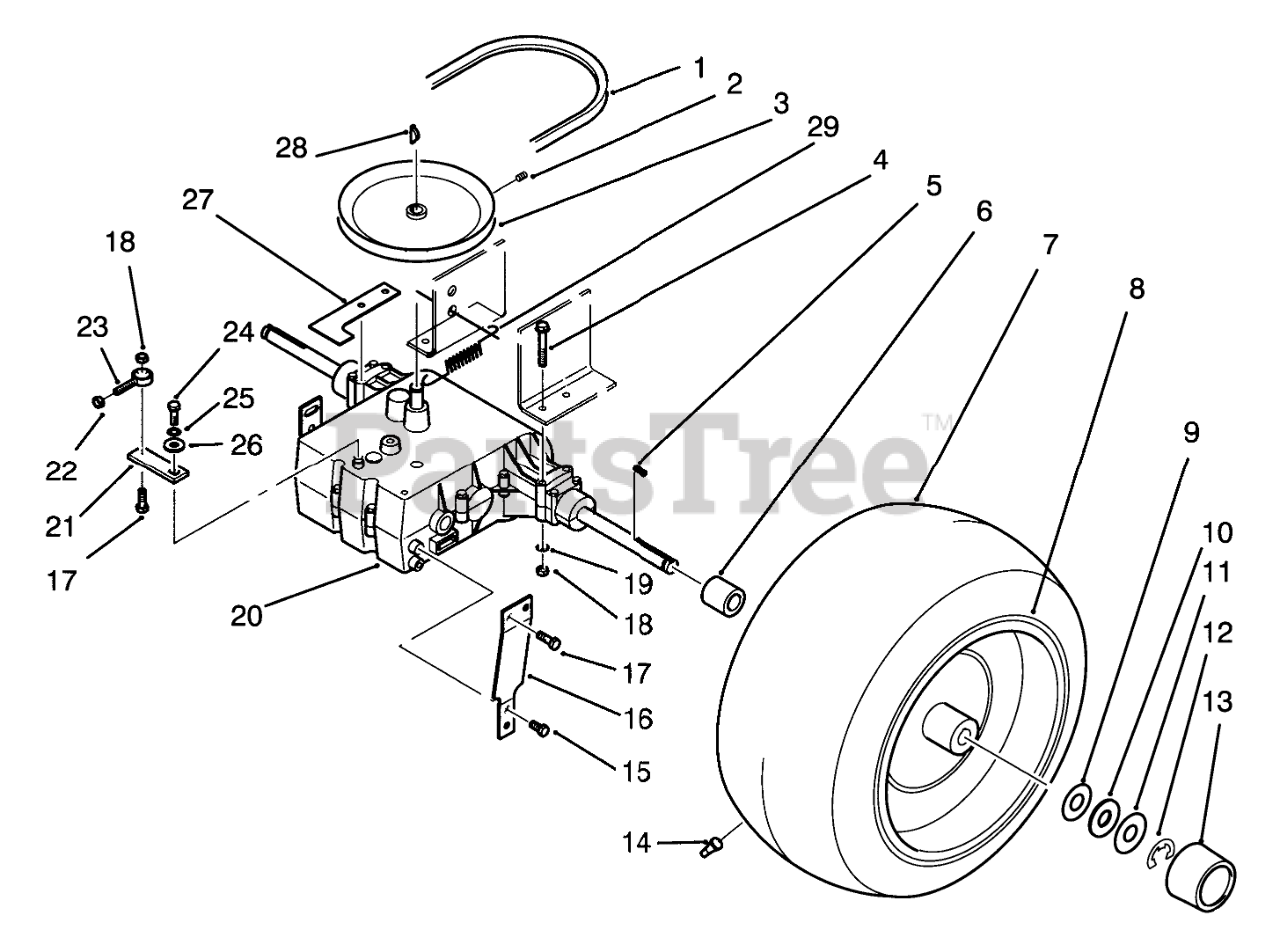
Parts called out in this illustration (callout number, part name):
1	BELT-V
2	SCREW-SQ HD SET
3	PULLEY-TRANS R
4	SCREW-HH
5	SQ KEY
6	LH AXLE SPACER
7	TIRE (20 X 10.00-10)
9	WASHER
10	WASHER-SHIM
11	WASHER-WHEEL
12	E-RING
13	HUB CAP-FLAT BLACK
14	VALVE
15	Screw
16	STRAP R
17	SCREW-HH
18	NUT-LOCK, NI
19	WASHER-PLAIN
20	ASS'Y-TRANS 5-SPEED
21	ARM-TRANS. R
22	Nut
23	BALL-END
24	SCREW-HH
25	WASHER-LOCK
26	WASHER
27	STOP-BRAKE R
28	KEY-HI-PRO
29	SPRING-EXTENSION
